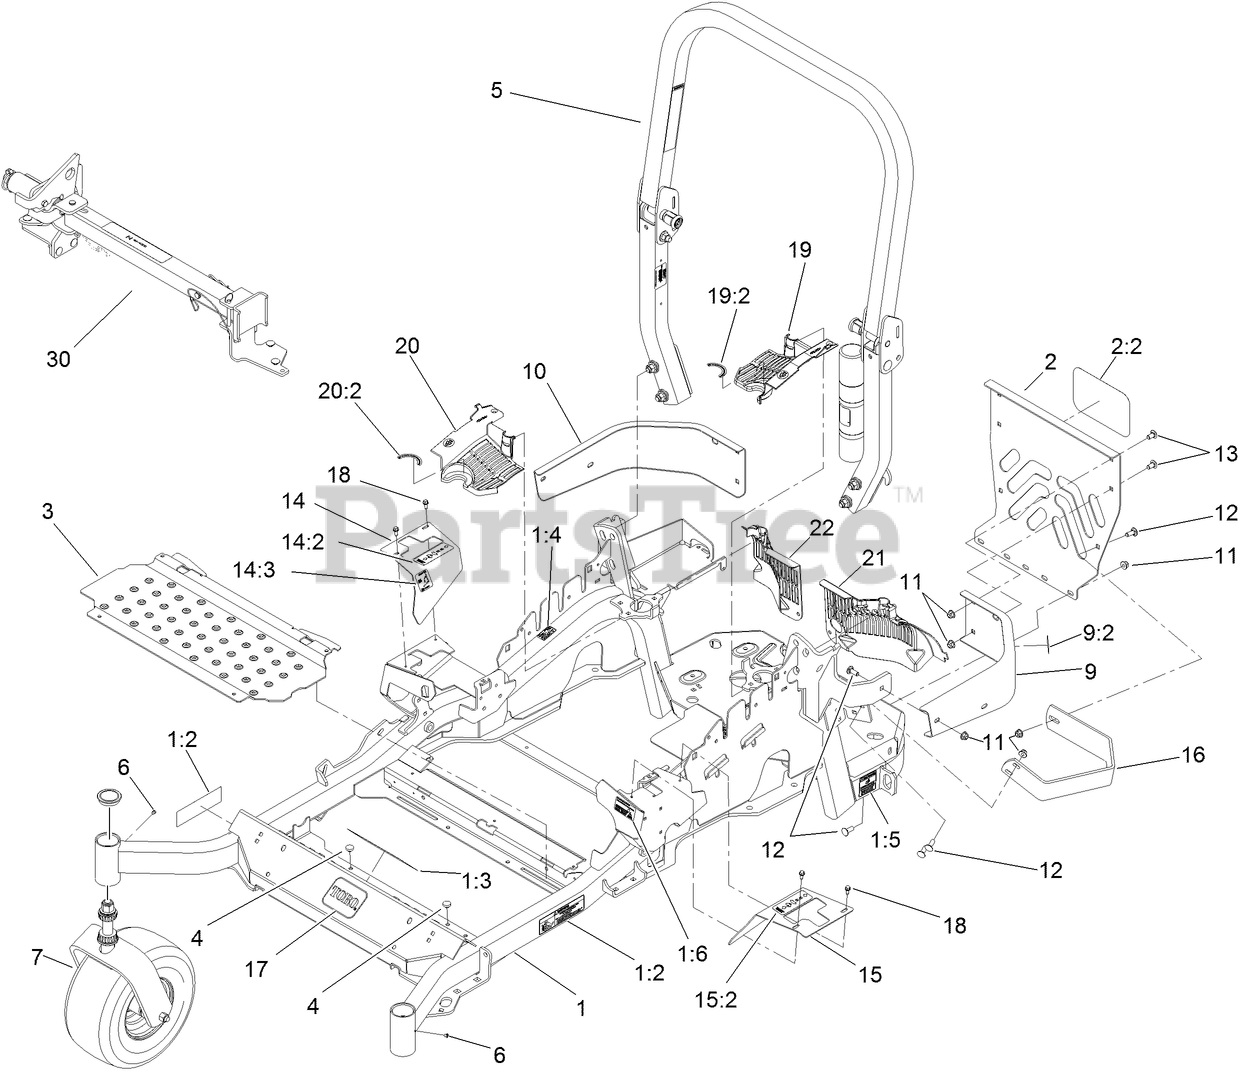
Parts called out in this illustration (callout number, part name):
1	MAIN FRAME ASM
1:2	DECAL-SLOPE
1:3	DECAL-CAUTION
1:4	DECAL-BELT DRIVE
1:5	DECAL-ARRESTER, SPARK
1:6	DECAL-FUEL FILL
2	REAR GUARD ASM
2:2	DECAL
3	FLOORPAN
4	BUMPER
5	ROPS ASM
7	Caster Wheel ASM
9	BUMPER-REAR, LH
9:2	DECAL-CAUTION
10	BUMPER-RH
11	NUT-HF, NI
12	SCREW-CARR
13	SCREW-CARR
14	RH MOTION CONTROL COVER ASM
14:2	DECAL-MOTION CONTROL
14:3	DECAL-PARK BRAKE
15	LH MOTION CONTROL COVER ASM
15:2	DECAL-MOTION CONTROL
16	GUARD-MUFFLER
17	DECAL
18	SCREW-HWH
19	LH HYDRO GUARD ASM
19:2	DECAL-HYDRO OIL
20	RH HYDRO GUARD ASM
20:2	DECAL-HYDRO OIL
21	GUARD-HYDRO, REAR (LH)
22	GUARD-HYDRO, REAR (RH)
30	Z STAND ASM
